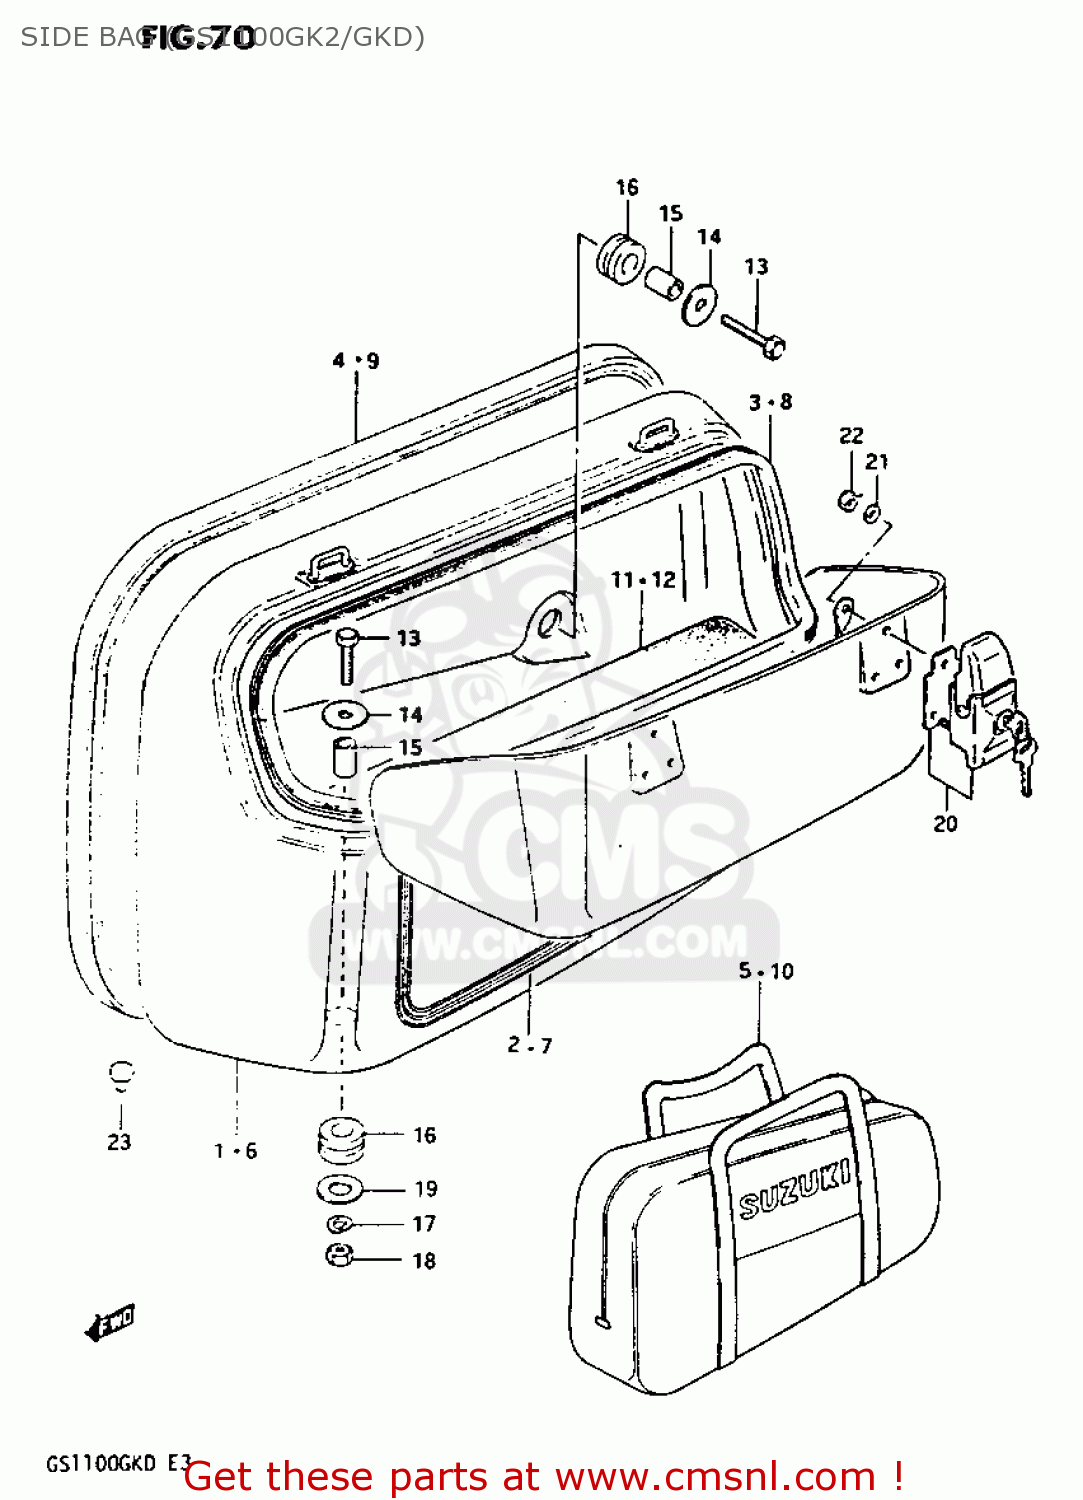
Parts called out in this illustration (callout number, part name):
1	SIDE BAG ASSEMBLY,RIGHT
2	TAPE SET,SIDE BAG,RIGHT
3	SEAL,TRAVEL TRUNK
4	MOLDING,SIDE BAG
5	LUGGAGE BAG RH
6	SIDE BAG ASSEMBLY,LEFT
7	TAPE SET,SIDE BAG,LEFT
8	SEAL,TRAVEL TRUNK
9	MOLDING,SIDE BAG
10	LUGGAGE BAG LH
11	CUSHION
12	CUSHION
13	BOLT
14	WASHER (6.5X29X1.6)
15	SPACER
16	CUSHION
17	WASHER,LOCK
18	NUT
19	WASHER (6.5X20X1.2)
20	LOCK,TRANK LID
21	WASHER 4MM
22	NUT 4MM
23	PLUG(OD:14)
